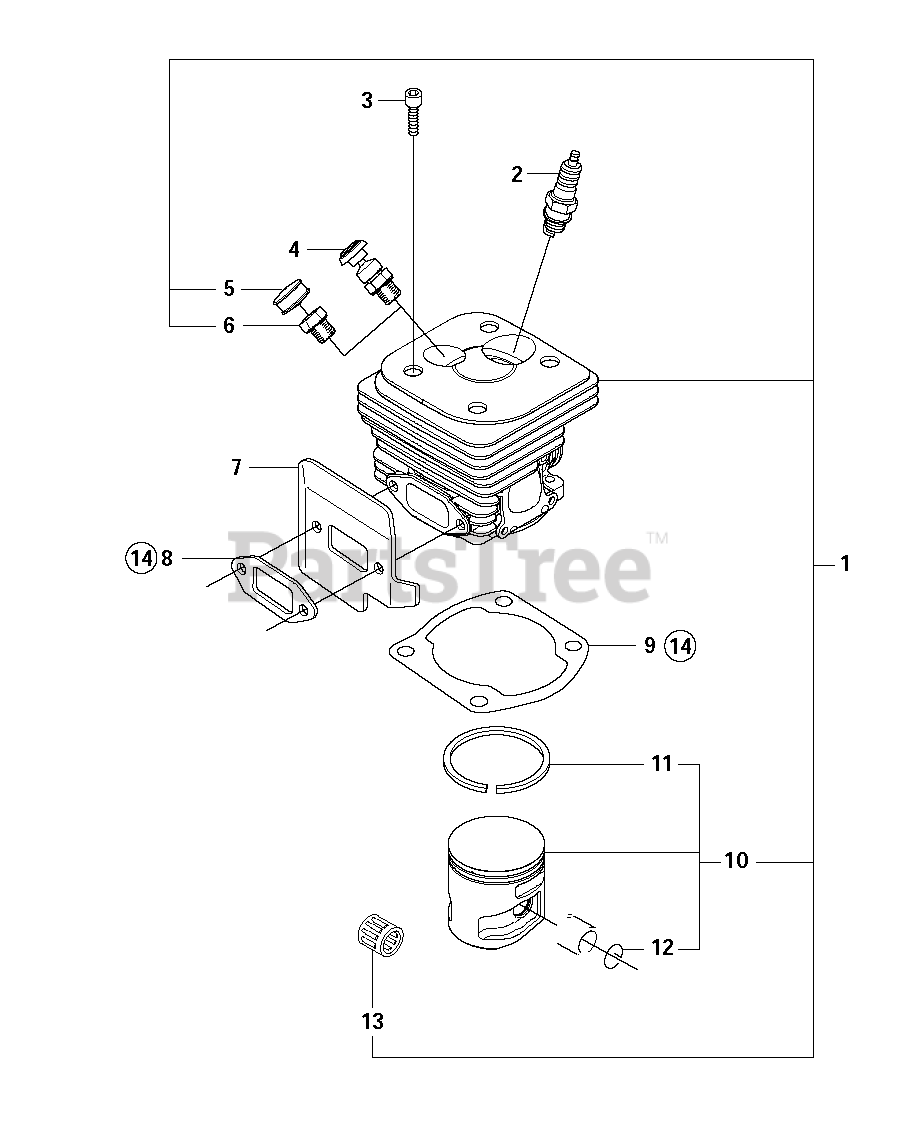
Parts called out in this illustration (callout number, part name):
1	CYLINDER ASSY
2	BPMR7A NGK SPARK PLUG
3	SCREW MC6S 5X25
4	VALVE
5	PLUG
6	CYLINDER PLUG
7	DEFLECTOR
8	GASKET
9	GASKET
10	PISTON ASSY
11	PISTON RING
13	SUPPORT BUSHING
14	GASKET SET
